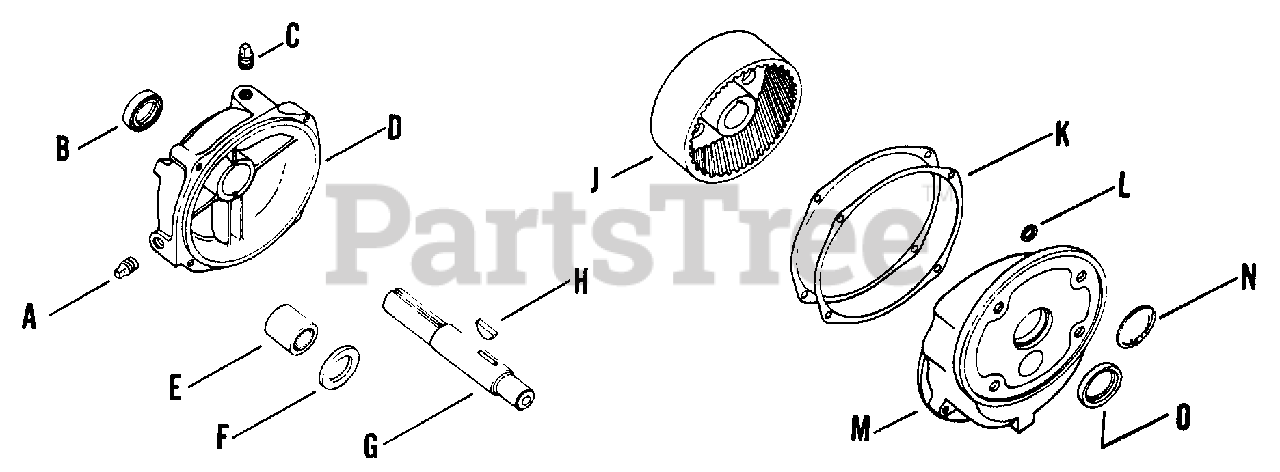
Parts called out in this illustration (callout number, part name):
A	PLUG,PIPE 1/4 NPTF SQUARE HD USE 25 139 53-S
C	PLUG - USE 41 139 01
D	COVER
F	BEARING
G	SHAFT - (#DSC)
H	KEY, 3/16" X 3/4"
J	GEAR - DISCONTINUED
K	GASKET - USE 234498
M	HOUSING - DISCONTINUED
